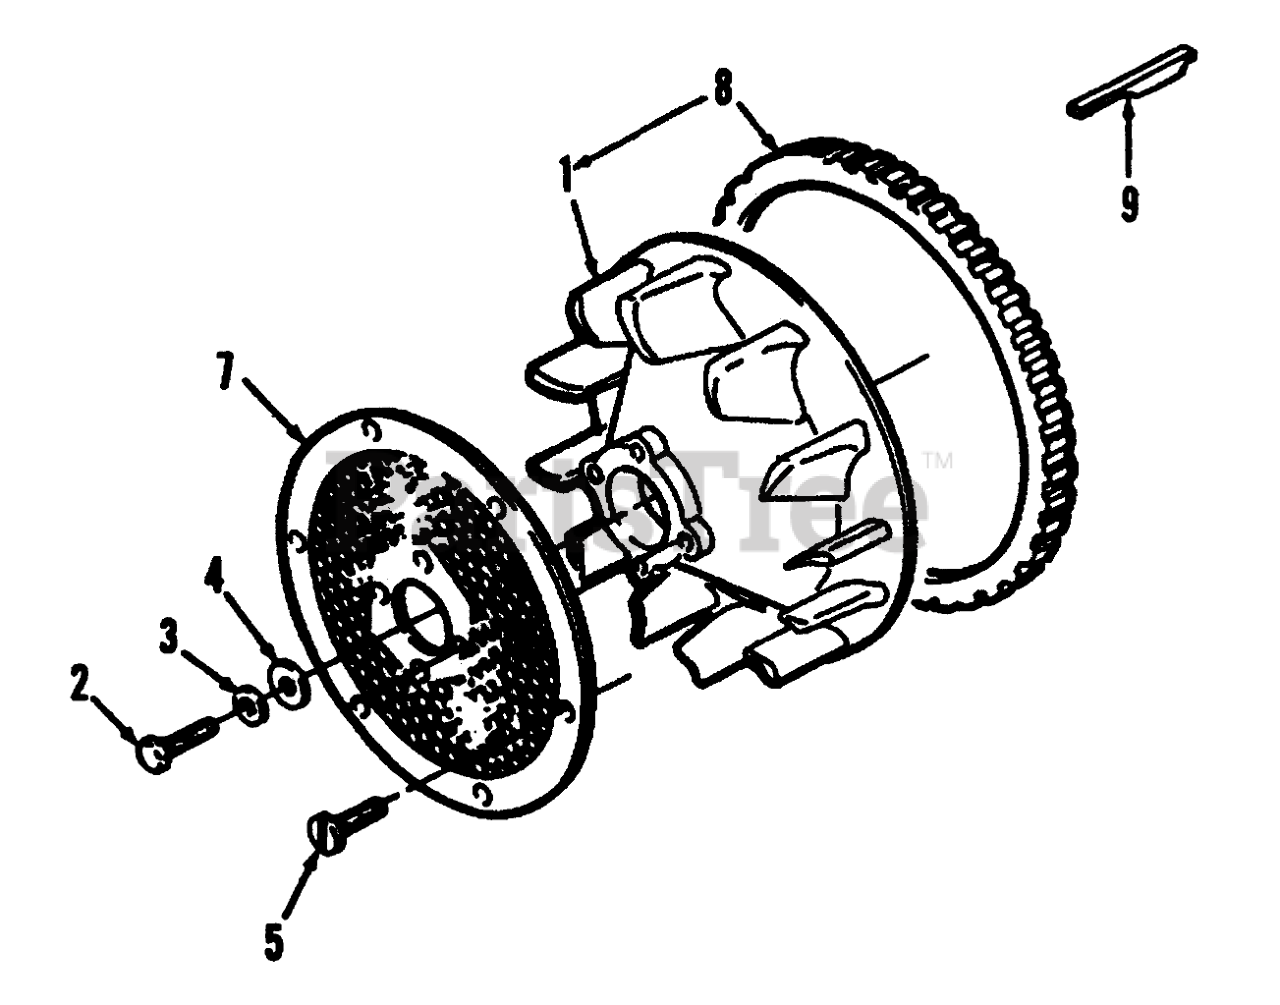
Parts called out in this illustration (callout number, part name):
1	Flywheel (Includes) Ring Gear)
2	Screw
3	WASHER-FLAT
4	WASHER-FLAT
5	Breather Tube
7	Screen
8	Gear-Ring
9	Key
